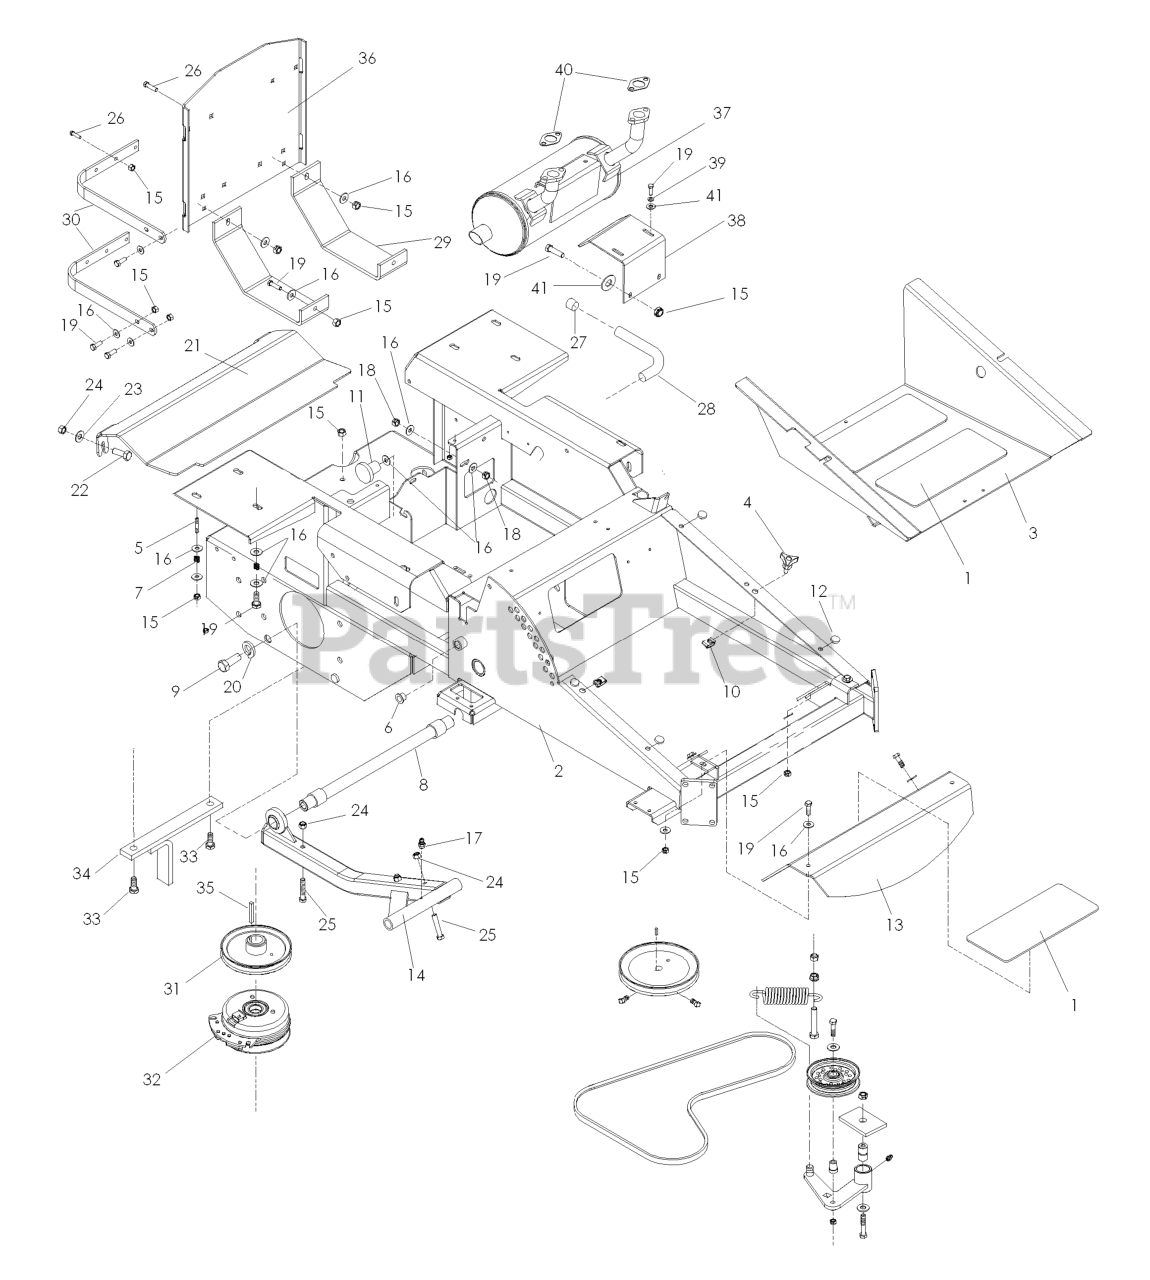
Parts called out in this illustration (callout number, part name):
1	ANTI-SKID PAD
2	IZ FRAME W/DECALS
3	IZ FOOTPLATE W/DECAL
4	KNOB W/STUD
5	STUD, 5/16C
8	STRUT MOUNT WELDMENT
9	HCS 5/8C X 2 GR.5
10	U-CLIP 5/16-18 NUT RETAINER
12	GROMMET, BUMPER
13	FOOTREST ORANGE
15	NUT 5/16 NYLOC
16	WASHER 5/16 FLAT
17	ZERK
18	NUT 5/16C CENTERLOCK
19	HCS 5/16C X 1
20	LOCKWASHER 5/8
21	REAR GUARD
22	SCREW 3/8C X 3/4 HEX CAP
23	WASHER 3/8 FLAT
24	NUT 3/8-16 NYLOC
25	HCS 3/8C X 2
26	RHSSNB 5/16C X 1.0
28	OIL DRAIN HOSE
29	SKID PLATE
30	ENGINE SHROUD BRKT
32	ELECTRIC CLUTCH W/CABLE
32	CLUTCH-200 FT LB(RPLS 5218-102
33	HCS 5/16C X 1 3/4
34	CLUTCH TIE DOWN
35	KEY, 1/4 SQ X 1 1/4
36	ENGINE GUARD
37	MUFFLER KAWASAKI GEN II
38	MUFFLER BRACKET BLACK
39	WASHER.LOCK.HVY.HLCL.SPR.5/16
40	EXHAUST GASKET - KAW
41	WASHER 5/16 FLAT
